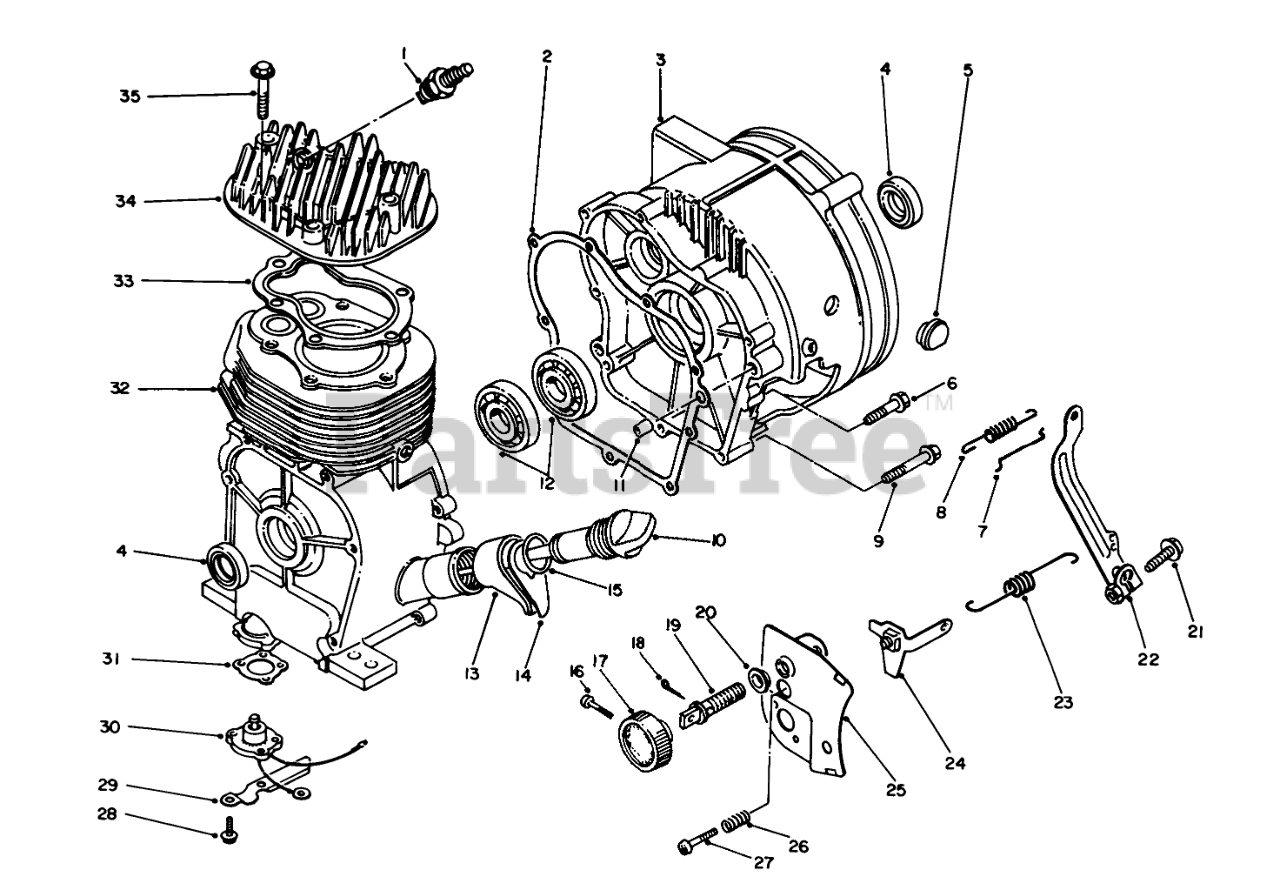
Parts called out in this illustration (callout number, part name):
1	SPARK PLUG
2	Gasket-Crankcase
3	Cover-Crankcase Side
4	OIL SEAL
5	Cap-Cover
7	Rod-Carburetor
8	SPRING
10	Gauge-Oil Level
12	Bearing
13	Plate-Oil Guide
14	Cover-Plate
15	O-RING
16	Screw
17	Knob-Throttle Control
19	SHAFT
20	Bushing
22	Lever-Control
23	Spring
24	Hook-Spring
25	Bracket-Throttle Control
26	Spring-Limit
27	SCREW
29	Plate-Guard
30	Sensor
31	GASKET
32	Cylinder Assembly
33	GASKET
34	Cylinder Head
